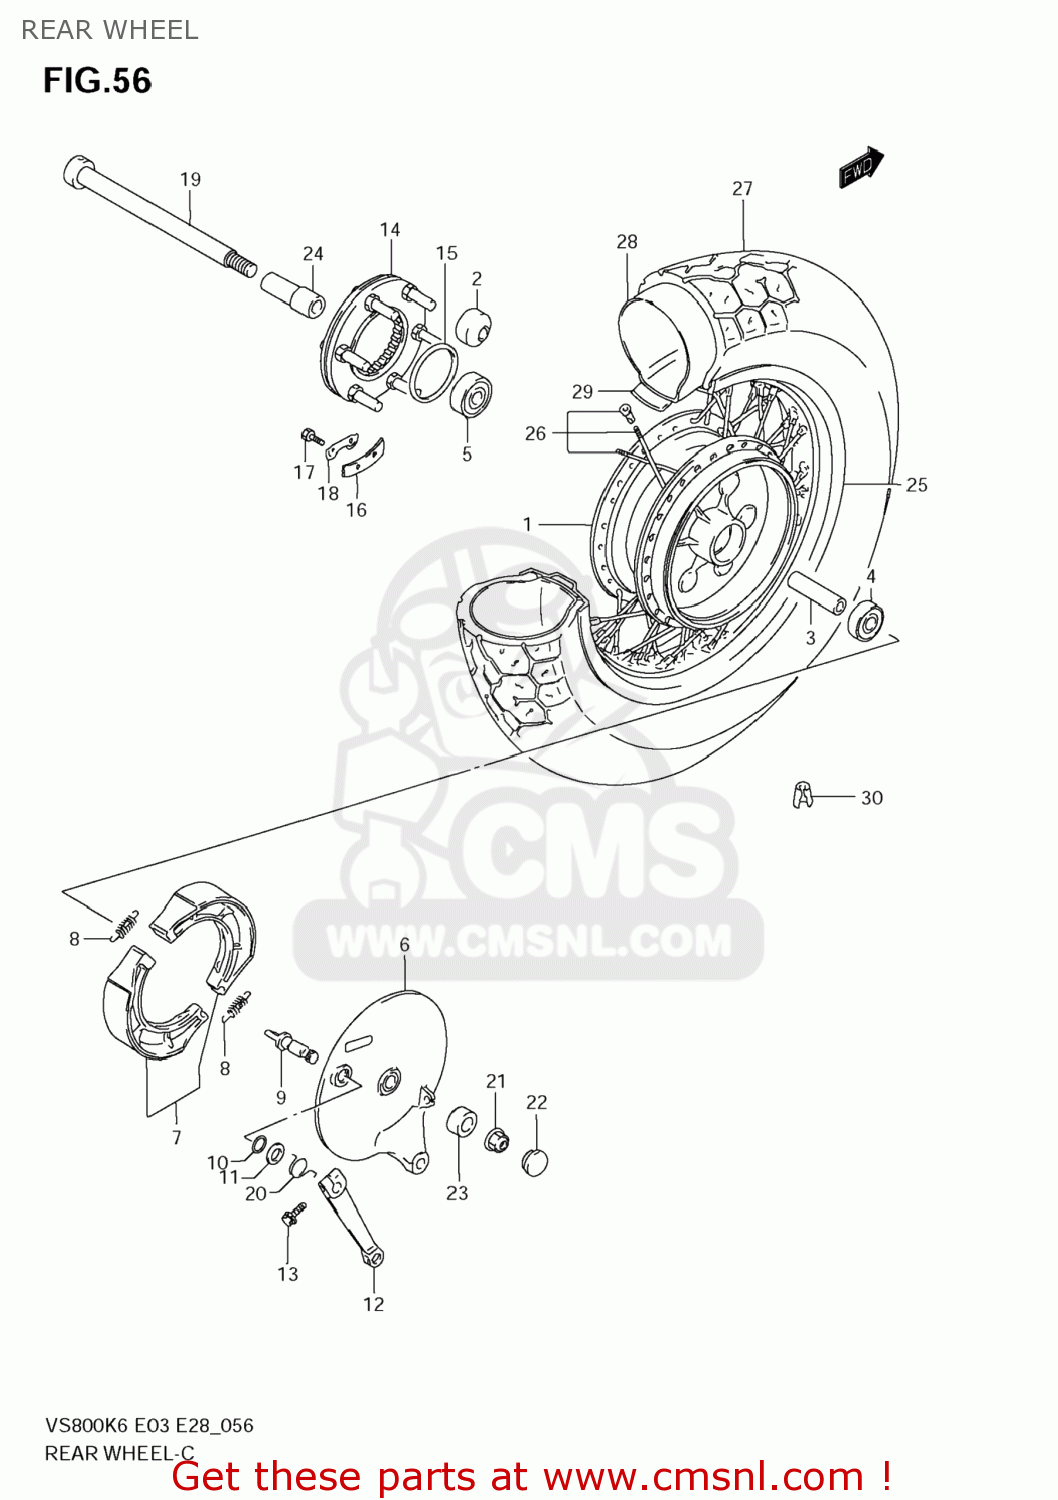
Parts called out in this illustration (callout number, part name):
1	HUB SET,RR
2	BUSH
3	SPACER(17.5X25X80)
4	BEARING
5	BEARING
6	PANEL,RR BRAKE ANCHOR
7	SHOE SET,BRAKE (NAS)
8	SPRING,BRAKE SHOE
9	CAM,RR BRAKE
10	O RING(D:2.4,ID:14.8)
11	WASHER(15.5X24X1.6)
12	LEVER,RR BRAKE CAM
13	BOLT
14	JOINT ASSY,RR HUB DRIVEN
15	O RING(D:2.1,ID:65)
16	WASHER,THRUST(T:1.6)
17	BOLT(6X16)
18	WASHER
19	AXLE,RR
20	SPRING
21	NUT
22	CAP,RR AXLE,R
23	SPACER,RR AXLE,L
24	SPACER,RR AXLE,L
25	RIM,RR WHEEL MT(3.00X15 M/C)
26	SPOKE ASSY,RR WHEEL
27	TIRE,RR
28	TUBE ASSY,WHEEL INNER
29	PROTECTOR, INNER TUBE
30	BALANCER,WHEEL(15G)
